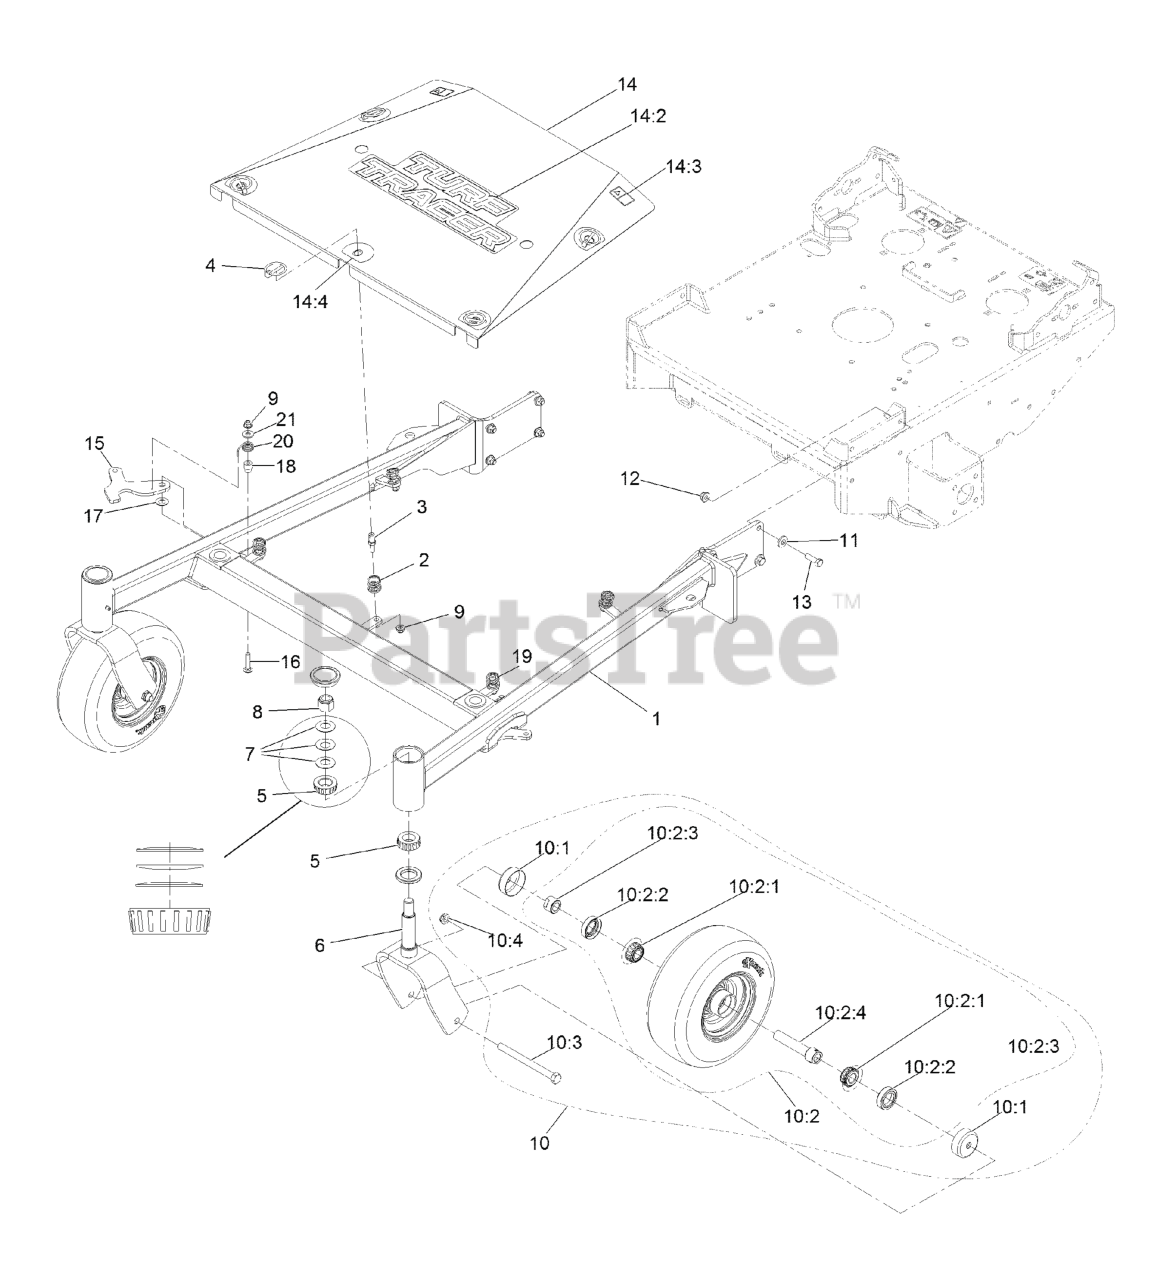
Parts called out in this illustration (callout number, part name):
1	ASM, FRONT FRAME W/ BEARI
3	PIN-SPRING
4	PIN-LYNCH
5	Cone-Bearing Tapered Roller
6	WLD, CASTER FORK
7	WASHER-BELLVILLE
8	NUT-LOCK, NI
9	NUT-HF, NI
10	ASM,WHEEL&BEARINGS
10:1	GUARD-SEAL
10:2	Wheel And Bearing ASM
10:2:1	BEARING-CONE, TAPERED ROLLER
10:2:2	SEAL-CASTER
10:2:3	SPACER-NUT
10:2:4	CASTER AXLE ASM
10:3	SCREW-HH
10:4	NUT-HEX
11	WASHER-BELLEVILLE
12	NUT-HF, NI
13	SCREW-HH
14	ASM, CENTER SHIELD W/ DEC
14:2	DECAL-TURF TRACER
14:3	DECAL-WARNING
14:4	DECAL-SCRATCH COVER
15	LATCH, DECK HEIGHT
16	BOLT-CARR
17	Washer-Plastic
18	Collar-Basket
19	Spring-Torsion, LH (Yellow)
20	Spring-Torsion, RH
21	WASHER-FLAT
